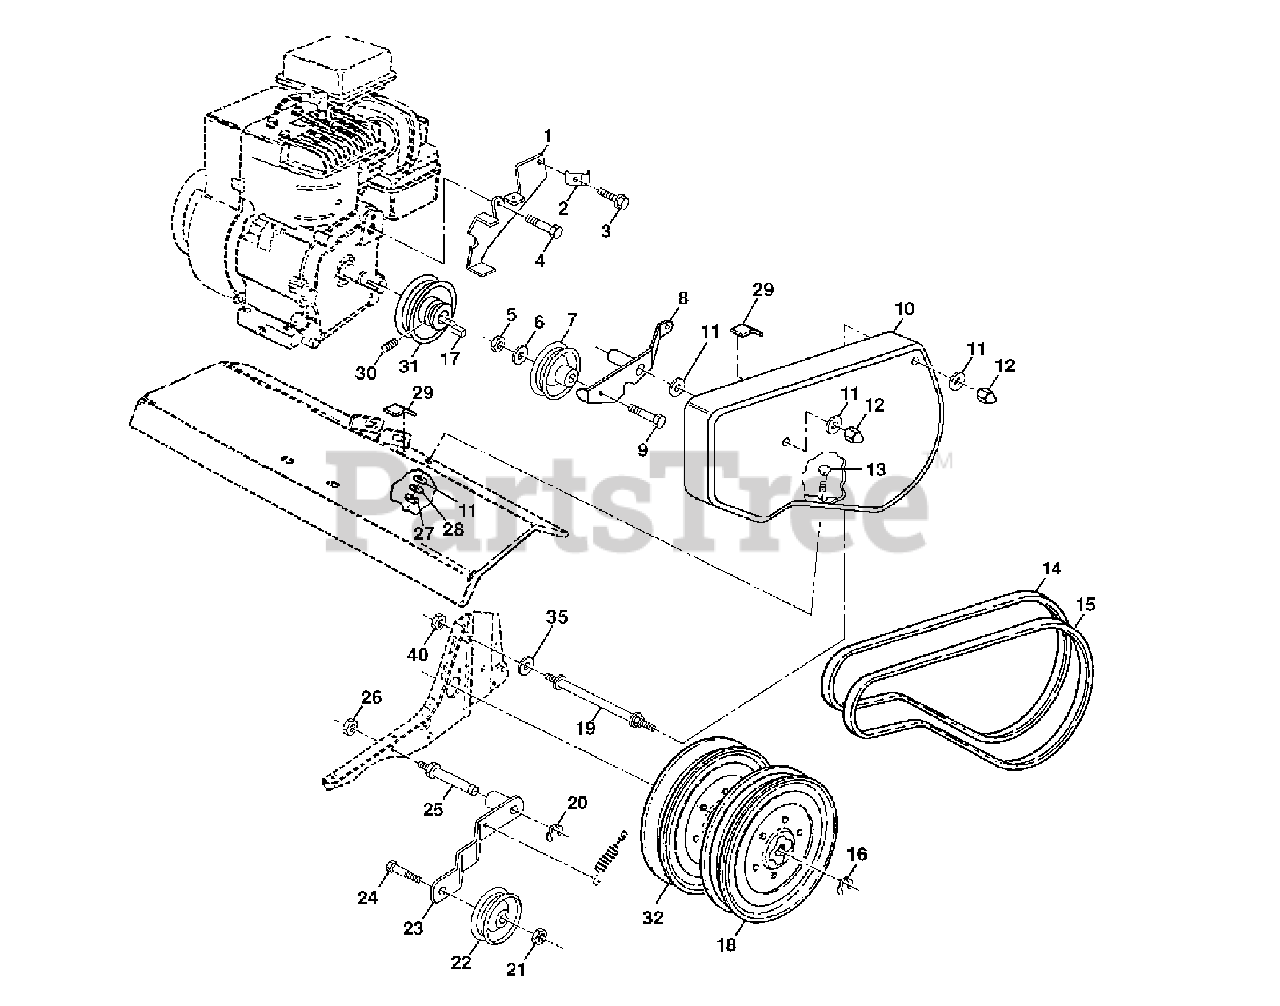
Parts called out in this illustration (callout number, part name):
1	Assembly, Bracket, Belt Guard
2	Clip, Cable
3	Screw, Hex, Washer Hd., Slotted, Thd. Cutting #10-24 x 1/2 Type D
4	Bolt, Hex 1/2-20 x 3/4
5	Nut, Hex 3/8-16
6	Washer 13/32 x 13/16 x 16 Ga.
7	Pulley, Idler, Reverse
8	Assembly, Arm, Reverse Idler
9	Bolt, Hex 3/8-16 x 1-3/4
10	Guard, Belt
11	Washer 9/32 x 5/8 x 16 Ga.
12	Nut, Cap 1/4- 20
13	Bolt, Carriage 1/4-20 x 3/4
14	V-Belt (Forward Motion)
15	V-Belt (Reverse)
16	Ring, Retainer
17	Key, Square
18	Pulley, Flat, Trans.
19	Bolt, Belt Guard
20	Ring, Klip
21	Nut, Hex, Jam 3/8-16
22	Pulley, Idler
23	Arm, Idler
24	Bolt, Hex 3/8-16 x 1-1/4
25	Shaft, Idler Arm
26	Nut, Hex, Jam 5/16-18
27	Nut, Fin Hex 1/4-20
28	Washer LK Hvy Helical 1/4
29	Pad, Idler
30	Screw, Set , Socket, Headless C.P. 1/4-20 x 1 /4
31	Sheave, Engine
32	Pulley, V-Groove, Trans.
35	Washer 9/32 x 7/8 x 16 Ga.
40	Nut Keps Hex 1/4-20
